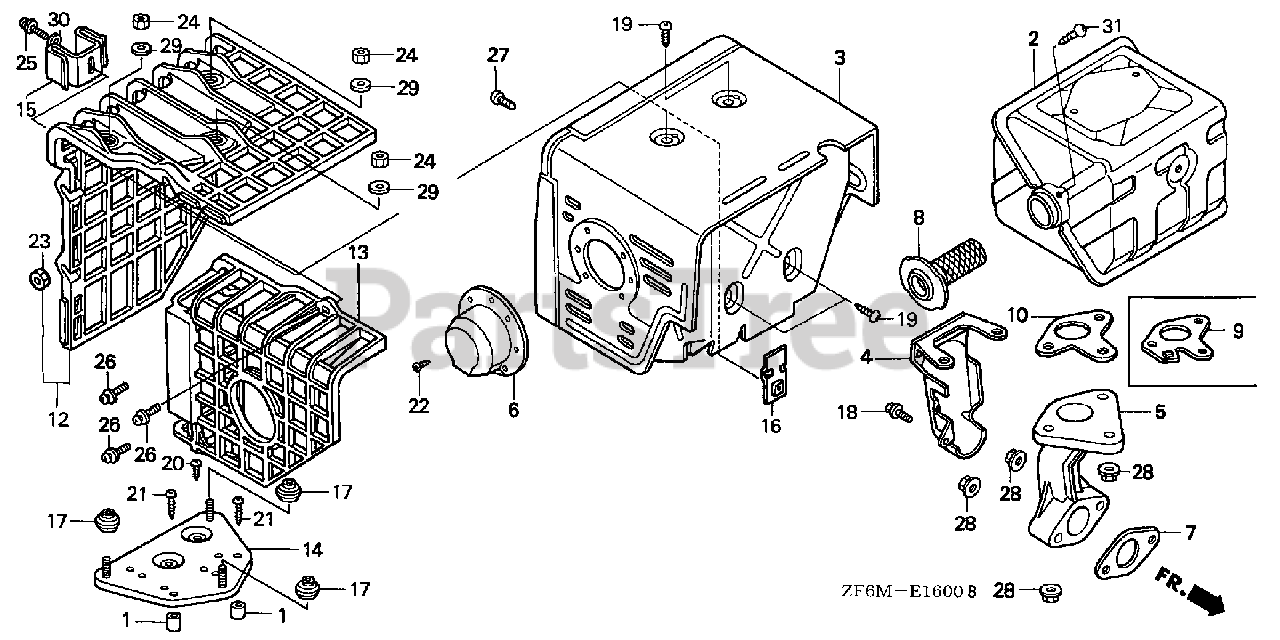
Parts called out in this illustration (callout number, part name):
2	MUFFLER (100DB)
3	PROTECTOR, MUFFLER
5	PIPE, EX.
6	CAP, MUFFLER
7	GASKET, EX. PIPE
8	ARRESTER, SPARK
9	GASKET, MUFFLER (ARRESTER)
19	SCREW, TAPPING (5X8)
22	SCREW, TAPPING (4X6)
27	SCREW, TAPPING (6X10)
28	NUT, FLANGE (8MM)
31	SCREW, TAPPING (5X8)
